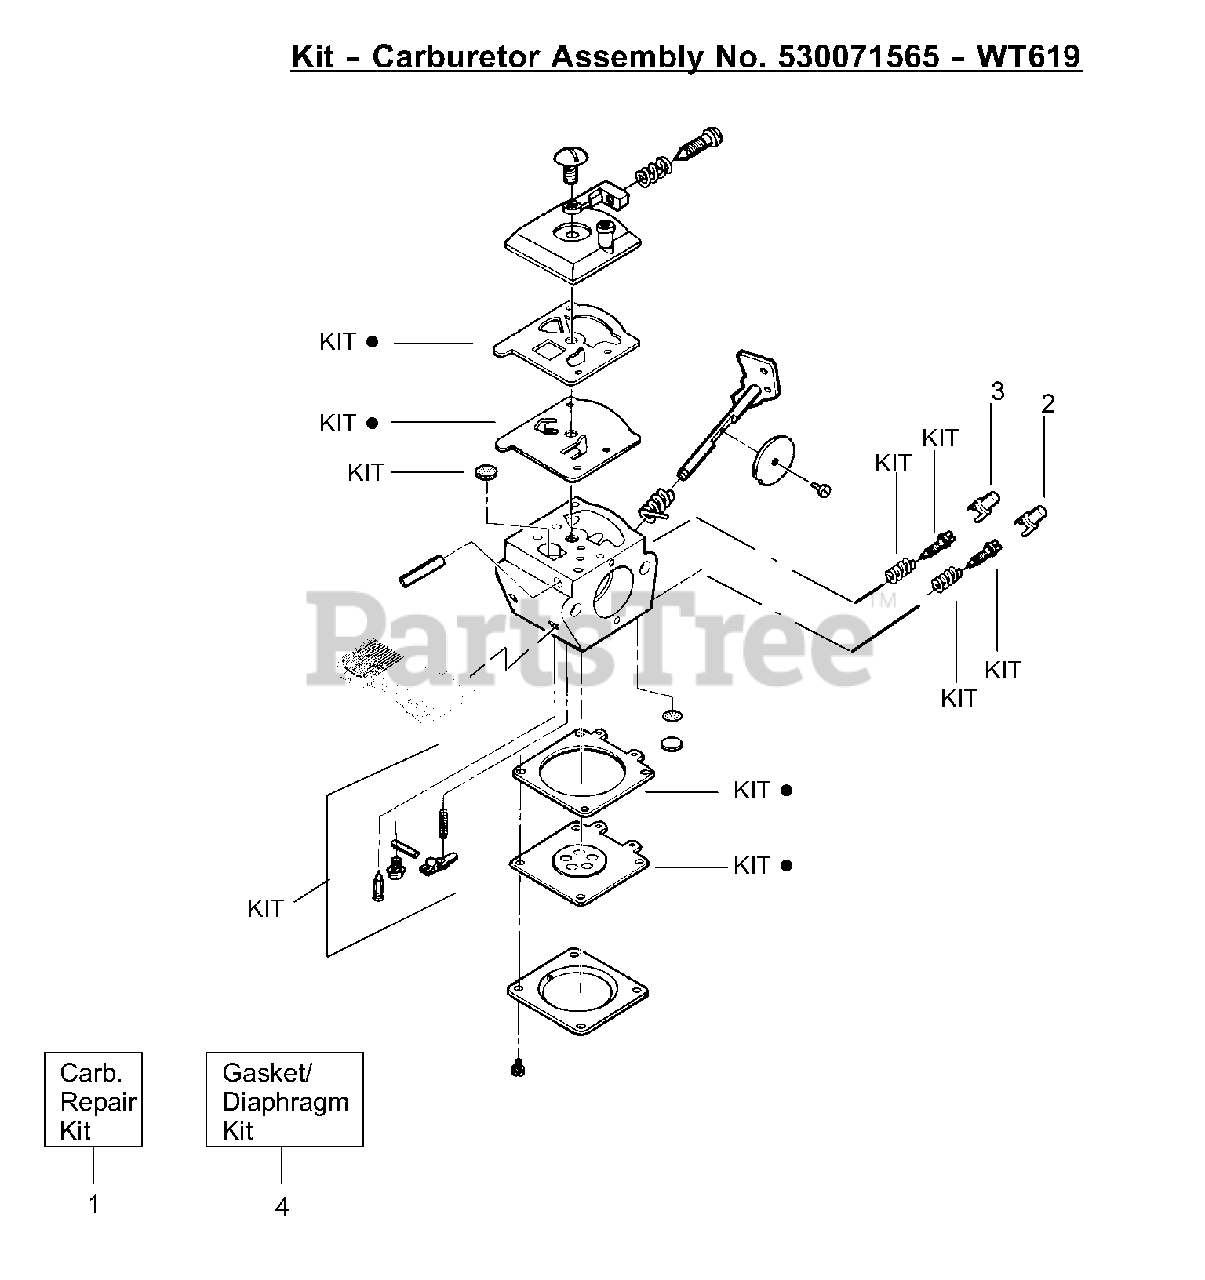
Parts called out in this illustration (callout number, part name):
1	Carburetor Repair Kit
2	Limiter Cap -low (tan)
3	Limiter Cap-high (brown)
4	Gasket/Diaphragm Kit
530071565	Carburetor Assembly (WT619)
